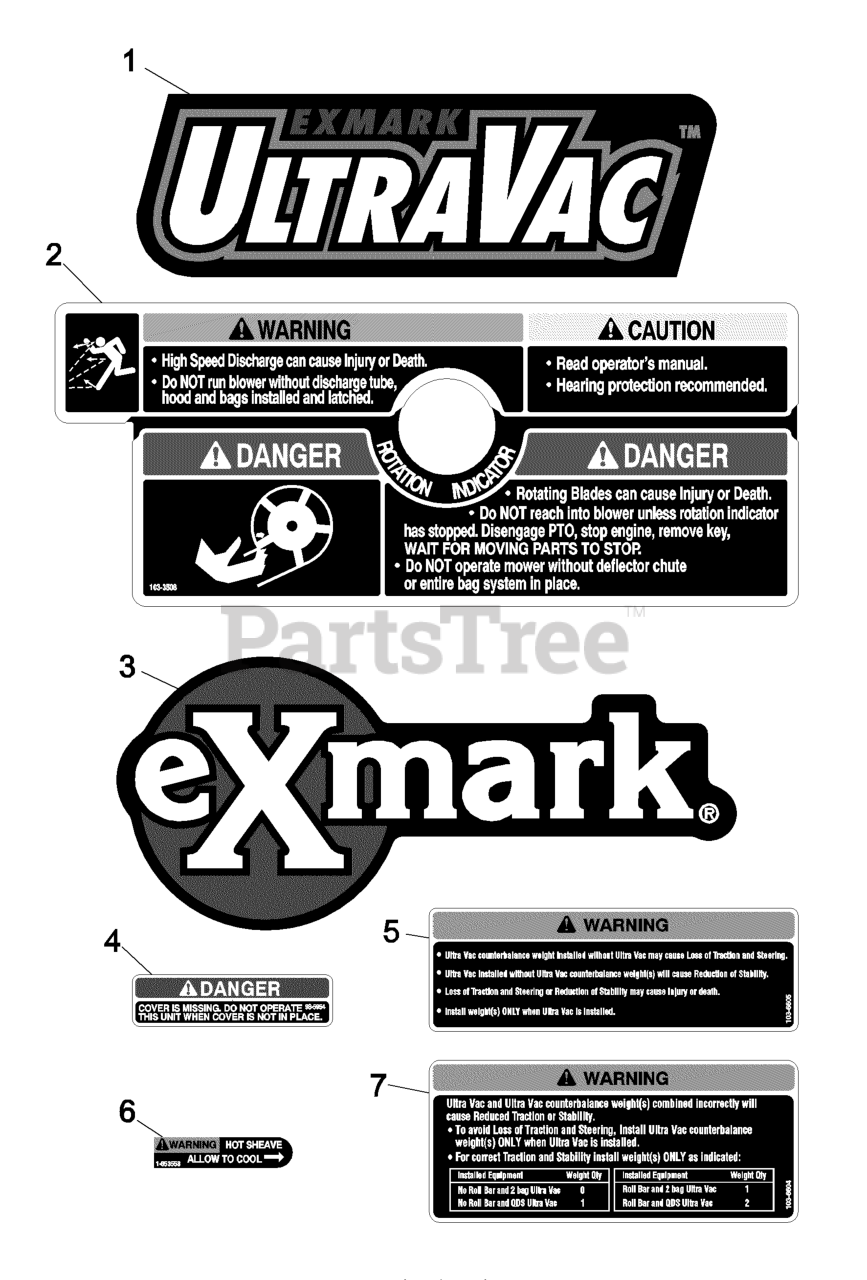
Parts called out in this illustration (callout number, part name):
1	DECAL, ULTRAVAC
2	DECAL-WARNING
3	DECAL, EXMARK LOGO
4	DECAL-COVER, MISSING
5	DECAL,WEIGHT
6	DECAL-WARNING
7	DECAL,WEIGHT
